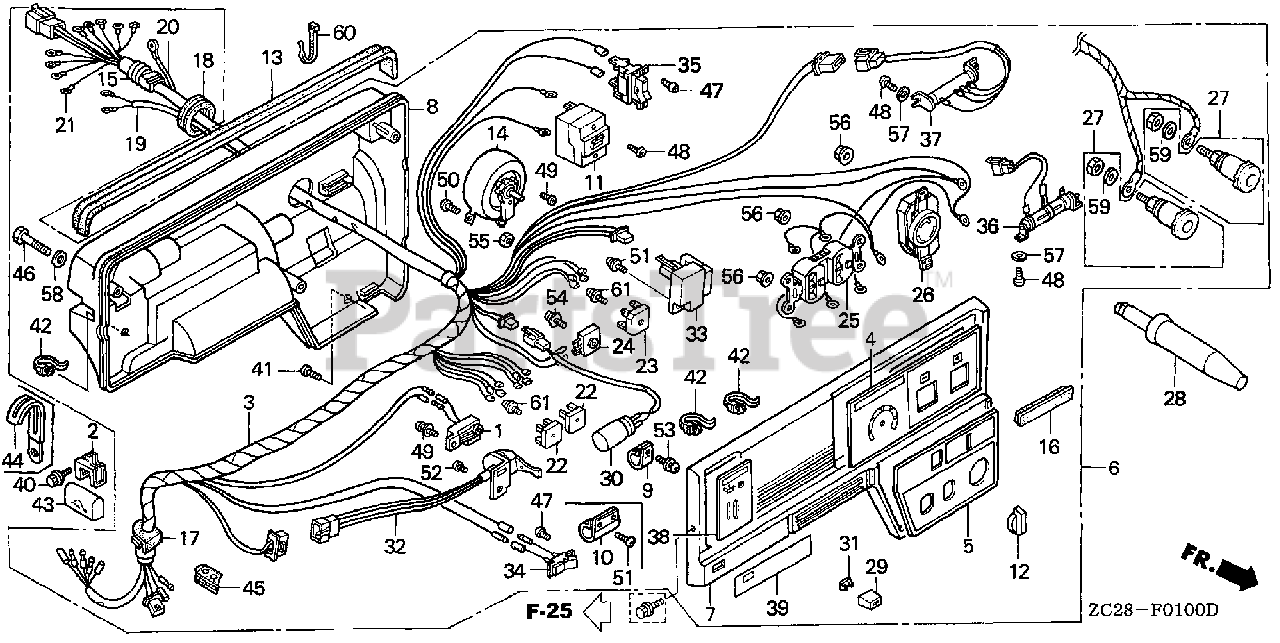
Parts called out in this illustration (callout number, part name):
1	ALERT UNIT, OIL
2	CLIP, WIRE
3	WIRE HARNESS ASSY.
3	WIRE HARNESS ASSY. (EW-A)
4	MARK, CURRENT CONTROL
5	MARK, A.C. OUT
6	BOX ASSY., CONTROL *R8* (BRIGHT RED)
6	BOX ASSY., CONTROL *R8* (EW-A) (BRIGHT RED)
6	BOX ASSY., CONTROL *R8* (EW-A) (BRIGHT RED) (NOT AVAILABLE)
7	PANEL, CONTROL *R8* (BRIGHT RED)
8	CASE, CONTROL *R8* (BRIGHT RED)
8	CASE, CONTROL *R280* (POWER RED)
9	HOLDER, CONDENSER
11	BREAKER, CIRCUIT (33.5A)
12	KNOB, ADJUSTING
13	RUBBER, CONTROL
14	RESISTOR, VARIABLE
15	GROMMET, A.C. WIRE
16	GROMMET, COVER
17	GROMMET, SWITCH WIRE
18	GROMMET, MAIN WIRE
19	WIRE A, WELDER TERMINAL (L=930MM 8X6) (+)
20	WIRE B, WELDER TERMINAL (L=700MM 6X6) (+)
21	WIRE C, WELDER TERMINAL (L=520MM 8X6) (-)
22	STACK, DIODE
23	DIODE
24	STACK, DIODE
25	RECEPTACLE (20A-125V)
25	RECEPTACLE (20A/125V)
26	RECEPTACLE (3-PRONG) (30A/125V)
27	RECEPTACLE, PANEL
28	CONNECTOR, MALE
29	KNOB, VALVE LEVER
30	CAPACITOR ASSY.
31	BUSH, CONTROL KNOB
32	SWITCH ASSY., ENGINE STOP
33	THROTTLE UNIT ASSY., AUTO
34	SWITCH ASSY., AUTO THROTTLE
35	SWITCH ASSY.
36	RESISTOR, ADJUSTABLE
37	RESISTOR
38	MARK, ENGINE SWITCH
39	MARK, AUTO-THROTTLE
40	BOLT, FLANGE (6X12) (CT200)
41	SCREW, GLOVE BOX
42	TIE, CABLE
43	TUBE, WIRE
44	CLIP, WIRE HARNESS
45	GROMMET, TUBE
46	BOLT, FLANGE (6X40)
47	SCREW, PAN (3X6)
48	SCREW, PAN (4X6)
49	SCREW, PAN (4X8)
50	SCREW, PAN (4X10)
51	SCREW-WASHER (5X12)
52	SCREW-WASHER (4X10)
53	SCREW-WASHER (5X14)
54	SCREW-WASHER (5X20)
55	NUT, HEX. (4MM)
56	NUT, FLANGE (4MM)
57	WASHER, PLAIN (4MM)
59	WASHER, PLAIN (8MM)
60	TIE, CABLE
61	SCREW-WASHER (4X20)
